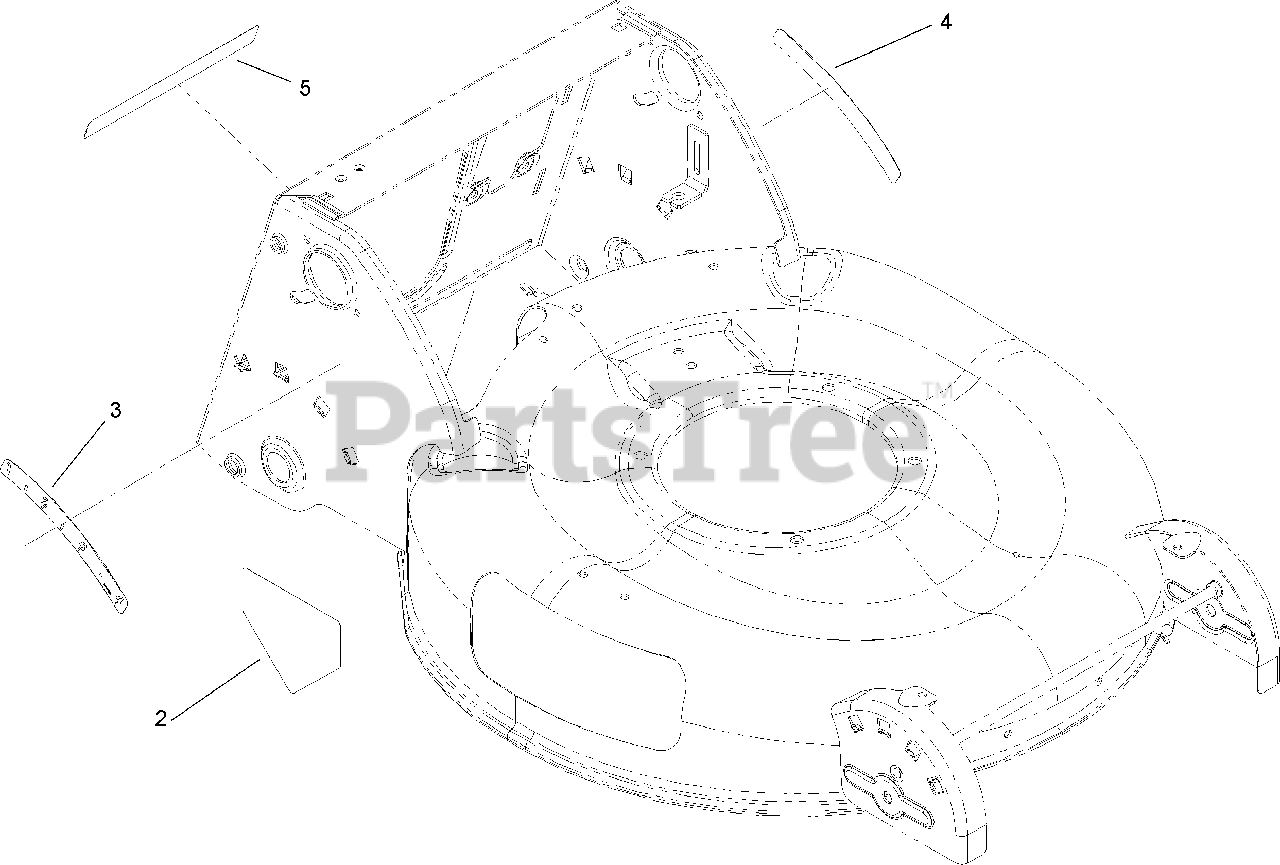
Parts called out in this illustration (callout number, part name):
2	DECAL-DANGER
3	DECAL-HOC, RH
4	DECAL-HOC, LH
5	DECAL-SAFETY
